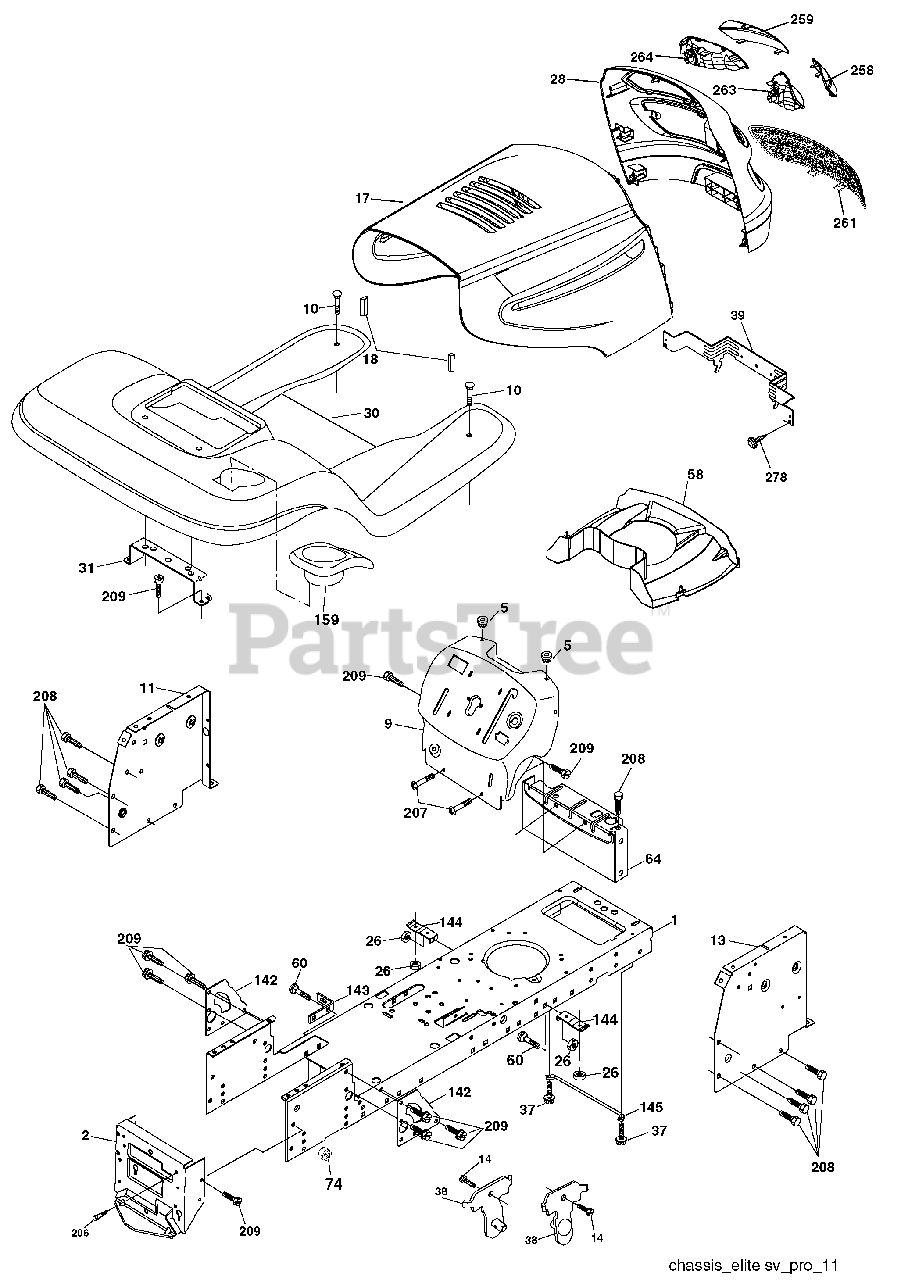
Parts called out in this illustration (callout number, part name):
1	Chassis
2	Drawbar
5	Bumper Hood/Dash
9	Dash P/L
10	Bolt Carriage 3/8-16 x 1
11	Panel Dash LH
14	Screw Thdrol. 3/8-16 x 1/2
17	Hood
18	Bumper Hood
26	Nut Lock Hex w/Ins. 3/8-16 unc
28	Grille/Lens Asm.
31	Bracket Fender
37	Screw Thdrol. 6/16-18 x 1/2 TYT
38	Bracket Asm. Pivot Mower Rear
39	Bracket Pivot
58	Duct Air
60	Bolt Rdhd. Sqnk. 3/8-16 unc x 1
64	Dash Lower STLT
74	Nut Crownlock 3/8-16 unc
142	Plate Reinforcement STLT
143	Bracket Swaybar Chassis
144	Bracket Footrest
145	Rod Pivot Chassis/Hood
159	Cupholder
206	Bolt Shoulder 5/16-18
207	Screw Thdrol. 5/16-18 x 1/2
208	Screw Thdrol. 3/8-16 x 1/2
209	Screw Hexwsh. Thdr. 3/8-16 x 3/4
228	Screw #10 x 0.750 BOS Thread
258	Lens Grille Pro RH
259	Lens Grille Pro LH
263	Bezel Grille RH
264	Bezel Grille LH
264	Plug BTN Blk.
264	Plug Domed Plastic
